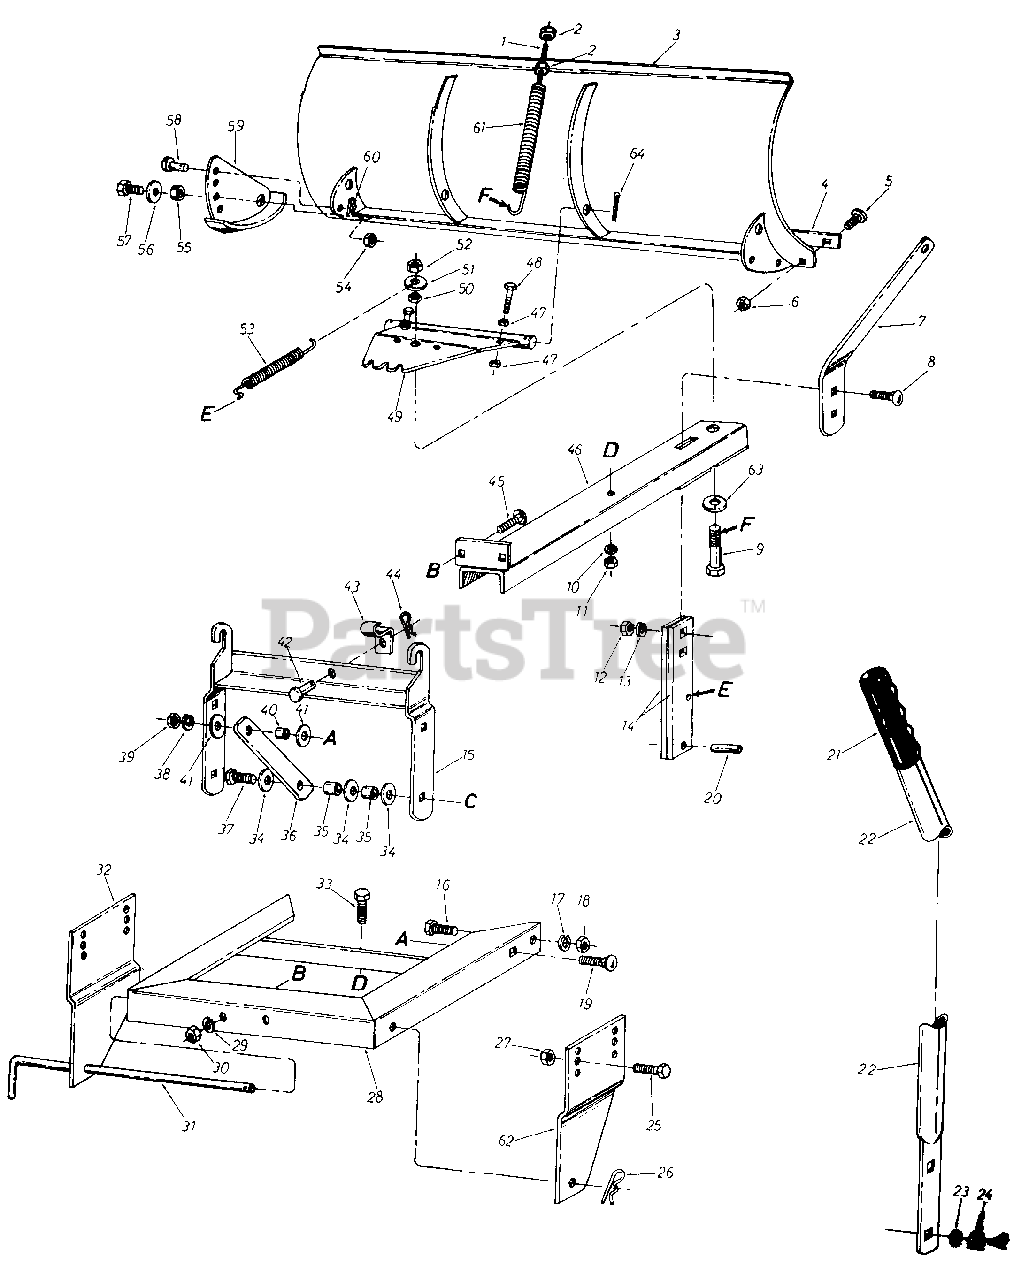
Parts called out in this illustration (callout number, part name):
1	Hex Bolt 3/8-16 x 4.50"
2	Hex Nut 3/8-16 Thd.*
3	42" Snow Blade Ass'y.
4	Wear Plate
5	Carriage Bolt 5/16-18 x .75" Lg.*
6	Hex . Cent. L.-Nut 5/16-18 Thd.
7	Lock Extension Bar
8	Carriage Bolt 3/8 16 x 1.25" Lg.*
9	Hex Bolt 3/4-10 x 3.50" Lg.
10	L.-Wash. 1/2" I.D.*
11	Hex Nut 1/2-13 Thd.*
12	Hex Nut 3/8-16 Thd.*
13	L.-Washer3/8" I.D.*
14	Angle Lock Bar
15	Lift Bracket Ass'y.
16	Hex Bolt 1/2-13 x 1.00" Lg.*
17	L.-Wash. 1/2" I.D.*
18	Hex Nut 1/2-13 Thd.*
19	Carriage Bolt 3/8-16 x 1.25" Lg.*
20	Spiral Spring Pin 1/4" Dia. x 1.00" Lg.
21	Grip
22	Lift Handle Ass'y.
23	L.-Wash. 3/8" I.D.*
24	Hex Nut 3/8-16 Thd.*
25	Hex Bolt 5/16-18 x .75" Lg.*
26	Hair Pin Cotter
27	Hex Cent. L-Nut 5/16-18 Thd.
28	Hitch Ass'y.
29	L.-Wash. 3/8" I.D.*
30	Hex Nut 3/8-16 Thd.*
31	Hitch Rod
32	Mounting Plate-L.H.
33	Hex Bolt 1/2-13 x 1.25" Lg.*
34	Flatwasher 3/8" I.D.
35	Pivot Bushing
36	Blade Lift Arm
37	Hex Bolt 3/8-16 x 1.75" Lg.*
38	L.-Wash. 3/8" I.D.*
39	Hex Nut 3/8-16 Thd.*
40	Pivot Bushing
41	Flatwasher 3/8" I.D.
42	Clevis Pin 5/16" Dia. x 3/4" Lg.
43	Hitch Retaining Bracket
44	Hair Pin Cotter
45	Carriage Bolt 3/8-16 x 1.00" Lg.*
46	Push Bar Ass'y.
47	Hex Nut 1/2-13 Thd.*
48	Hex Bolt 1/2-13 x 2.00" Lg.*
49	Pivot Ass'y.
50	Hex Jam Nut 3/4-10 Thd.
51	Flat Wash. 3/4" I.D.
52	Hex Ins. L.-Nut 3/4-10 Thd.
53	Spring-Angle Lock
54	Hex Lock Nut 3/8-16 Thd.
55	Pivot Bushing
56	Fl.-Wash. .385" I.D. x 1.00" O.D.
57	Hex Bolt 3/8-16 x .75" Lg.*
58	Clevis Pin 5/16" Dia. x .75" Lg.
59	Skid Ass'y.
60	Hair Pin Cotter
61	Blade Adjustment Spring
62	Mounting Plate-R.H.
63	Fl.-Wash. .810 I.D. x 2.00" O.D.
64	Cotter Pin 5/32 x 1-1/2" Lg.
